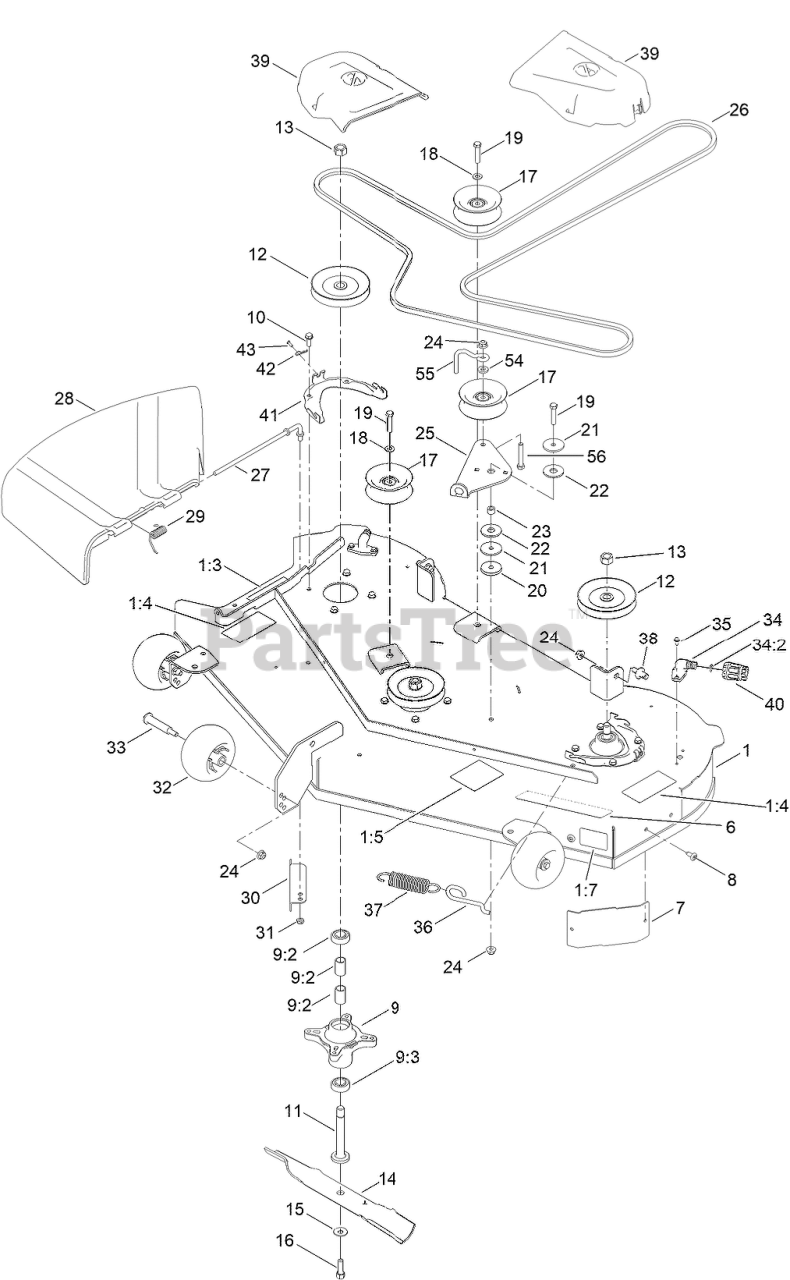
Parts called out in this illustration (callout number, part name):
1	50 INCH DECK AND DECAL ASM
1:3	DECAL-DANGER
1:4	DECAL-DANGER, DECK
1:5	DECAL-ROUTING, BELT
1:7	DECAL-SCALP, ANTI
6	DECAL - DECK
7	BAFFLE-CORNER
9	SPINDLE ASM
9:2	SPACER
9:3	BEARING-BALL
10	SCREW-TAPTITE
11	SHAFT-SPINDLE
12	PULLEY
13	NUT-HEX
14	BLADE-HI LIFT
15	WASHER-BELLEVILLE
16	SCREW-HH
17	PULLEY-IDLER, FLAT
18	WASHER-FLAT
19	SCREW-HH
20	WASHER-PLAIN
21	WASHER-REBOUND
22	WASHER-FRICTION, COMPOSITE
23	SPACER
24	NUT-HF, NI
25	ARM-IDLER
26	V-BELT
27	ROD-PIVOT
28	DEFLECTOR-DISCHARGE
29	SPRING-TORSION
30	BAFFLE-CUTOFF
32	ROLLER-SCALP, ANTI
33	BOLT-SHOULDER
34	FITTING-WASHOUT
34:2	O-RING
35	SCREW-HWH
36	HOOK-RETURN SPRING
37	SPRING-EXTENSION
38	PIN-DECK
39	COVER-BELT
40	CONNECTOR-HOSE
41	BRACKET-COVER, BELT
42	PIN-HAIR
43	SCREW
54	SPACER-HUB, BLOWER
55	BELT GUIDE - IDLER
56	SCREW-HH
